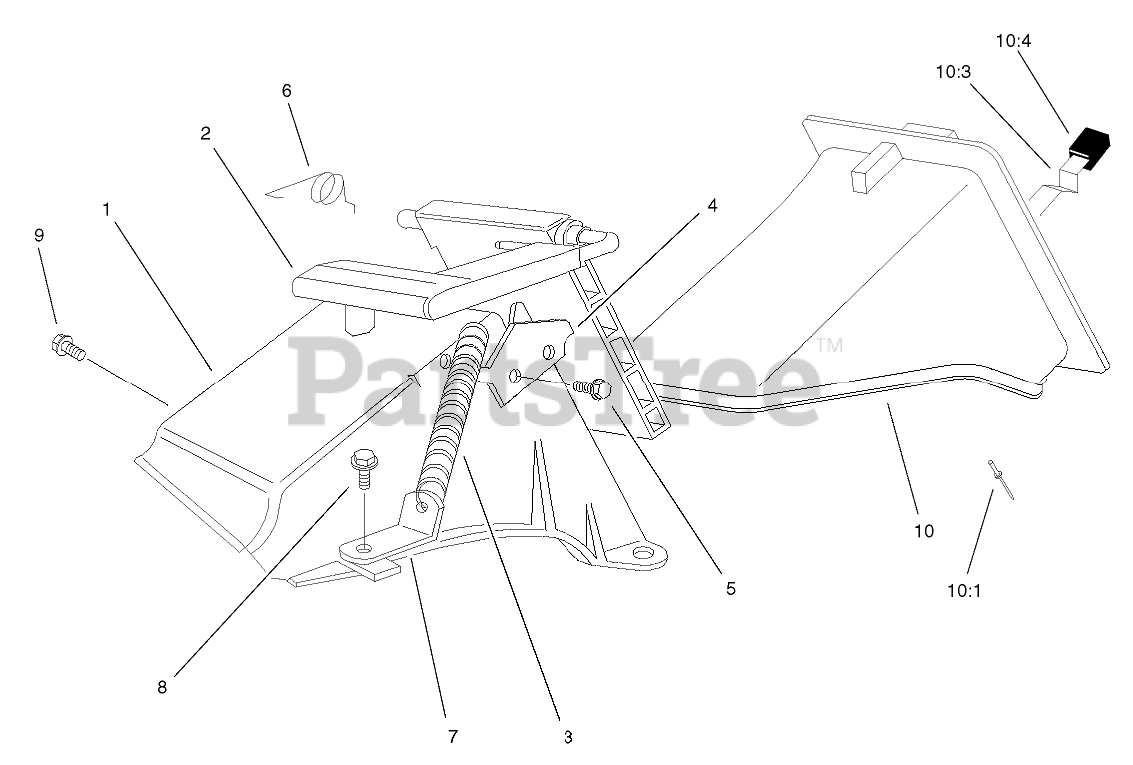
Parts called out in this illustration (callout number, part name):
1	TUNNEL-DISCHARGE
2	DISCHARGE DOOR ASM
3	SPRING-DOOR
4	LATCH-PLATE
5	SCREW-PLASTITE
6	RETAINER-DOOR
7	BRACKET-SPRING
8	SCREW-HWH
9	SCREW AND WASHER ASM
10	DISCHARGE PLUG ASM
10:1	RIVET-HEAD, FLAT
10:3	LATCH-PLUG, DISCHARGE
10:4	GRIP-LATCH
